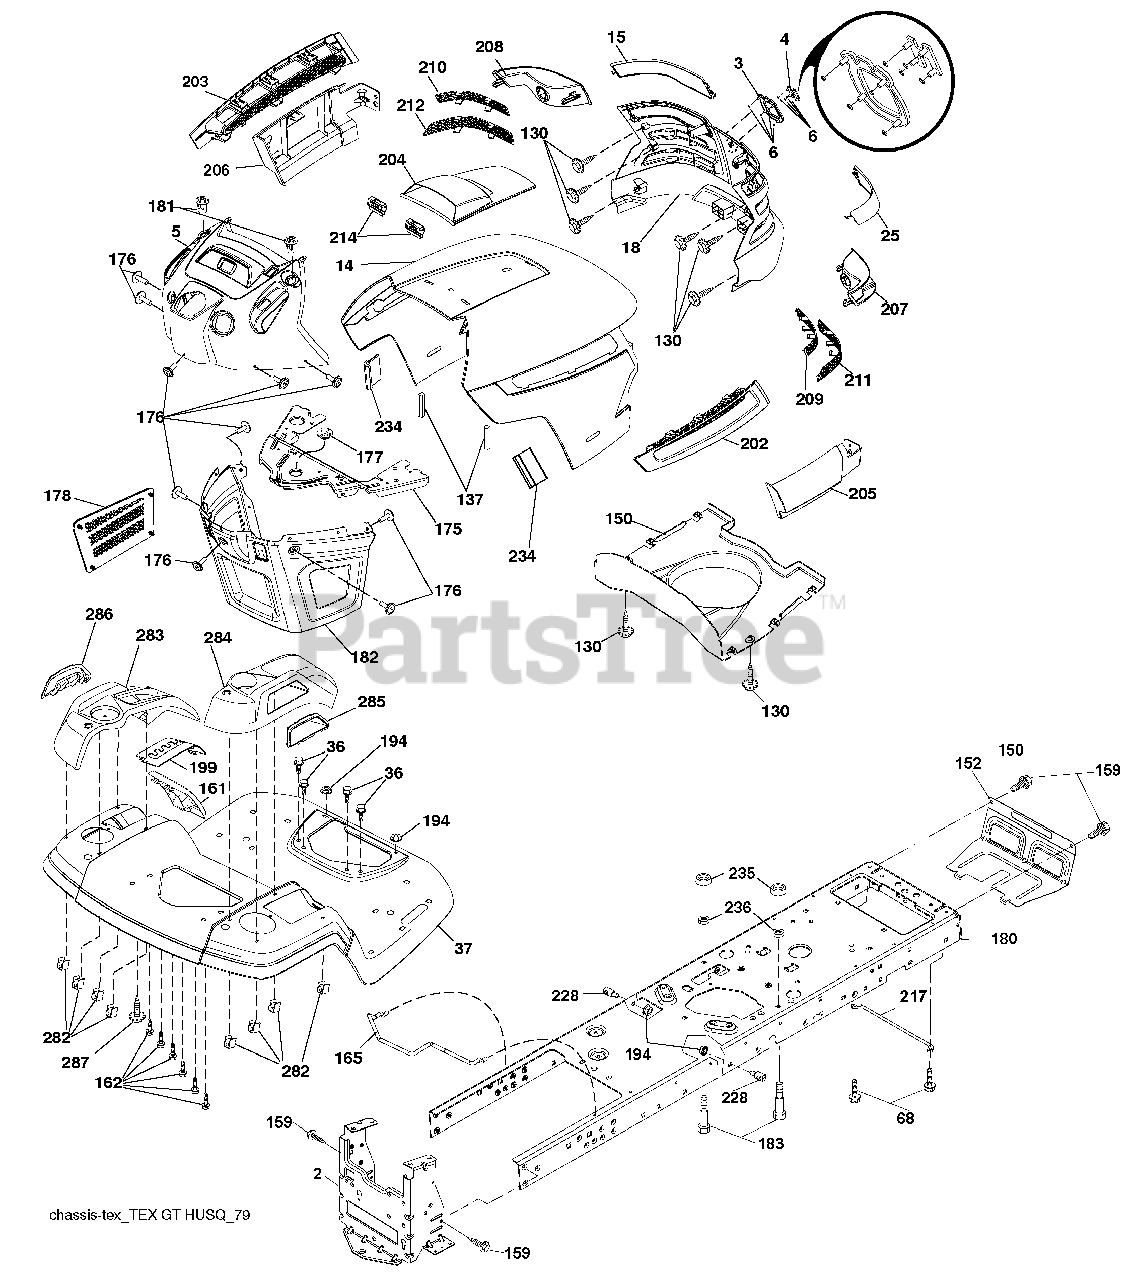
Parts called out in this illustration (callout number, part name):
3	Trim, Husq.
4	Logo
5	Dash
14	Hood
18	Grille/Lens Asm.
36	Screw 5/16-18 x 3/4
68	Screw Thdrol 5/16-18 x 1/2
130	Screw 10 x 0.750 BOS Thread
137	Bumper Dash
152	Shield Browning
159	Screw 3/8-16 x 3/4
161	Window Fuel
162	Screw Hex Wsh Hi-Lo 1/4 x 1/2 unc
165	Support Tank Rear
175	Crossmember
176	Screw 10-24 x 5/8
177	Bushing Steering
178	Cargo Net Asm.
180	Chassis
181	Bushing Mtg. Fender Crgo
182	Dash Lower
183	Bolt 5/16-18 x 1-1/4
194	Nut Lock Hex Flange 5/16-18
199	Plate Deck Lift
202	Vent Side Hood RH
203	Vent Side Hood LH
204	Vent Top Hood
205	Skirt Hood Side RH
206	Skirt Hood Side LH
209	Insert Hex Top RH
210	Insert Hex Top LH
211	Insert Hex Bottom RH
212	Insert Hex Bottom LH
214	Clip Retainer Tinner
228	Stud Fastener
234	Bumper Hood
235	Spacer Fender
236	Nut Lock 5/16-18 unc
282	Clip Retainer Console
283	Console Deck Lift
284	Console Shift
285	Console Insert RH
286	Console Insert LH
287	Screw 1/4-20 X 3/8
